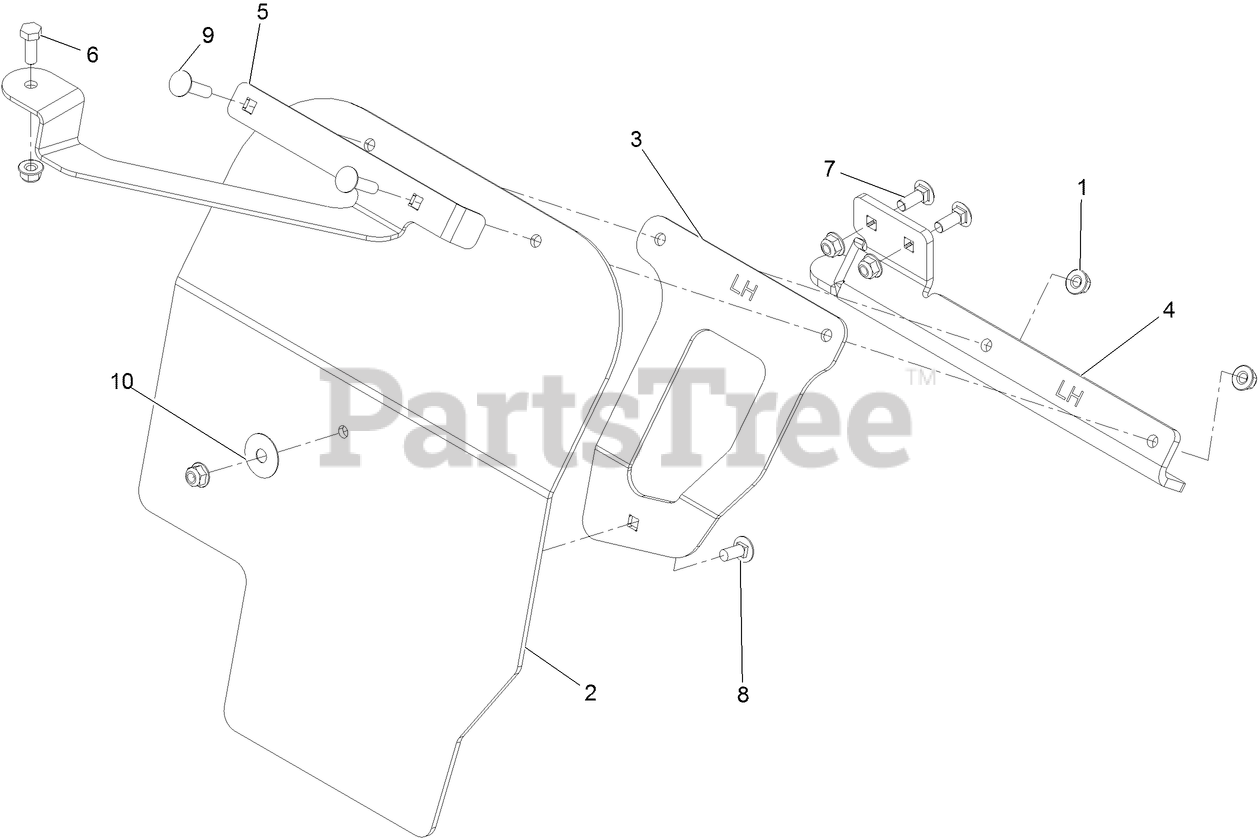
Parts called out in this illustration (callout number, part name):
1	NUT-HF, NI
2	LH MUD FLAP
3	SUPPORT, LH MUD FLAP
4	BRACKET, LH MUD FLAP
5	FORWARD SUPPORT, LH MUD FLAP
6	SCREW-HH
7	SCREW-CARR
8	SCREW-CARR
9	SCREW-CARR
10	WASHER-PLAIN
